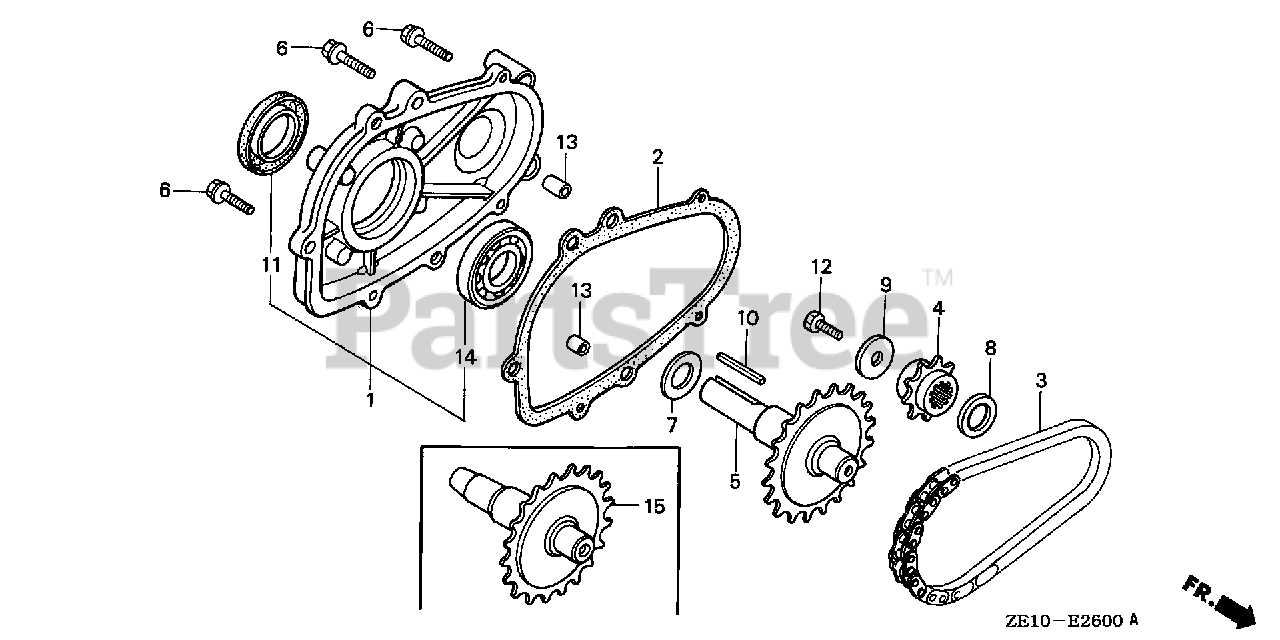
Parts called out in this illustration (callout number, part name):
1	COVER ASSY., CHAIN CASE
2	GASKET, CHAIN CASE COVER
3	CHAIN, P.T.O. DRIVE (DID317FM2-34LE)
4	SPROCKET, DRIVE (13T)
5	SHAFT, P.T.O. (26T)
6	BOLT, FLANGE (6X28) (CT200)
7	SPRING, THRUST
8	SPACER (20MM)
9	WASHER (8MM)
10	KEY (5X5X33) (YELLOW)
11	OIL SEAL (25X41X6)
12	BOLT, HEX. (8X22)
13	PIN, DOWEL (8X14)
14	BEARING, RADIAL BALL (6205)
